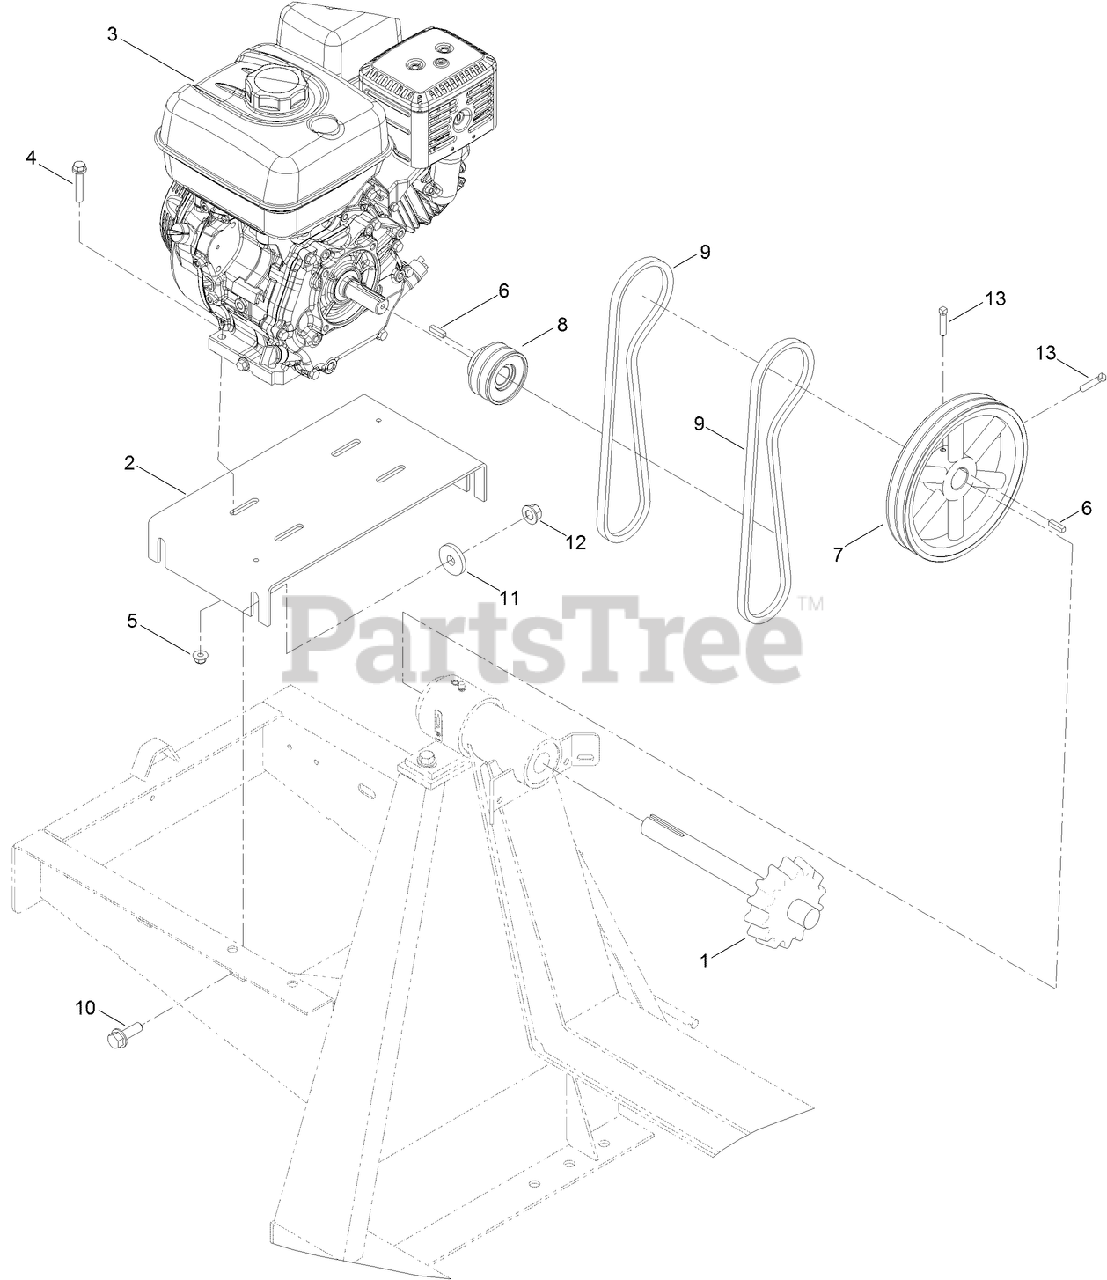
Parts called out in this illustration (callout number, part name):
1	SHAFT-DRIVE
2	BASE-ENGINE, 95CM
3	ENGINE-HONDA, GX240
4	SCREW-HHF
5	NUT-HF, NI
8	SHEAVE
9	BELT-V
10	SCREW-HHF
11	WASHER-FLAT
12	NUT-LOCK
13	SCREW-SET
